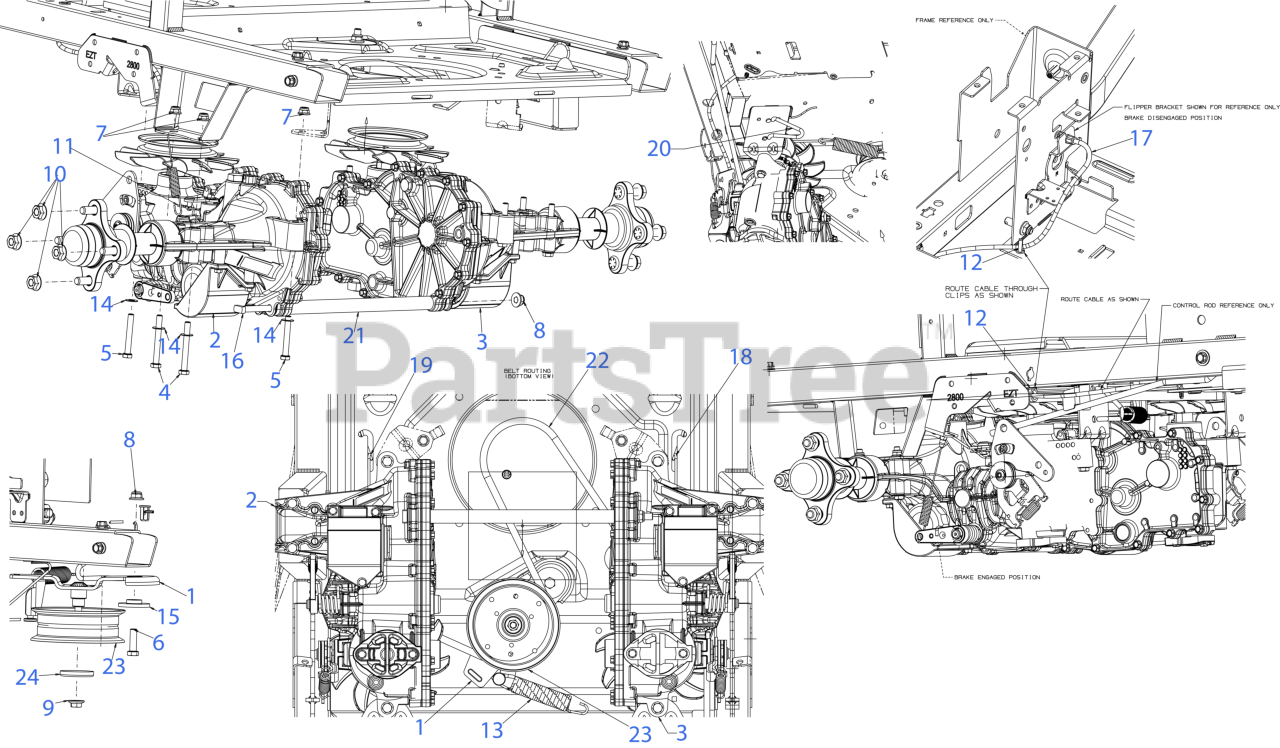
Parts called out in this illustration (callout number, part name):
1	DRIVE IDLER BRACKET
2	HYDRO TRANSMISSION (LH)
3	HYDRO TRANSMISSION (RH)
4	HEX SCREW 5/16-18 x 2.75
5	HEX SCREW 5/16-18 x 2.25 GR5
6	SCREW 3/8-16 x 1.25 GR5
7	FLANGE LOCK NUT 5/16-18
9	FLANGE LOCK NUT
10	HEX FLANGE NUT 7/16-14
11	BOW TIE COTTER PIN 1/4-5/16
12	CABLE RETAINER CLIP
13	EXTENSION SPRING .925 x 5.37
14	FLAT WASHER
15	SHOULDER SPACER
16	SUPPORT TUBE ROD
17	PARK BRAKE CABLE
18	HYDRO BYPASS ROD (RH)
19	HYDRO BYPASS ROD (LH)
20	IDLER SPRING HOOK
21	SUPPORT TUBE
22	TRANSMISSION DRIVE BELT A x 67
23	IDLER PULLEY 4.50" DIA
24	IDLER PULLEY CAP
